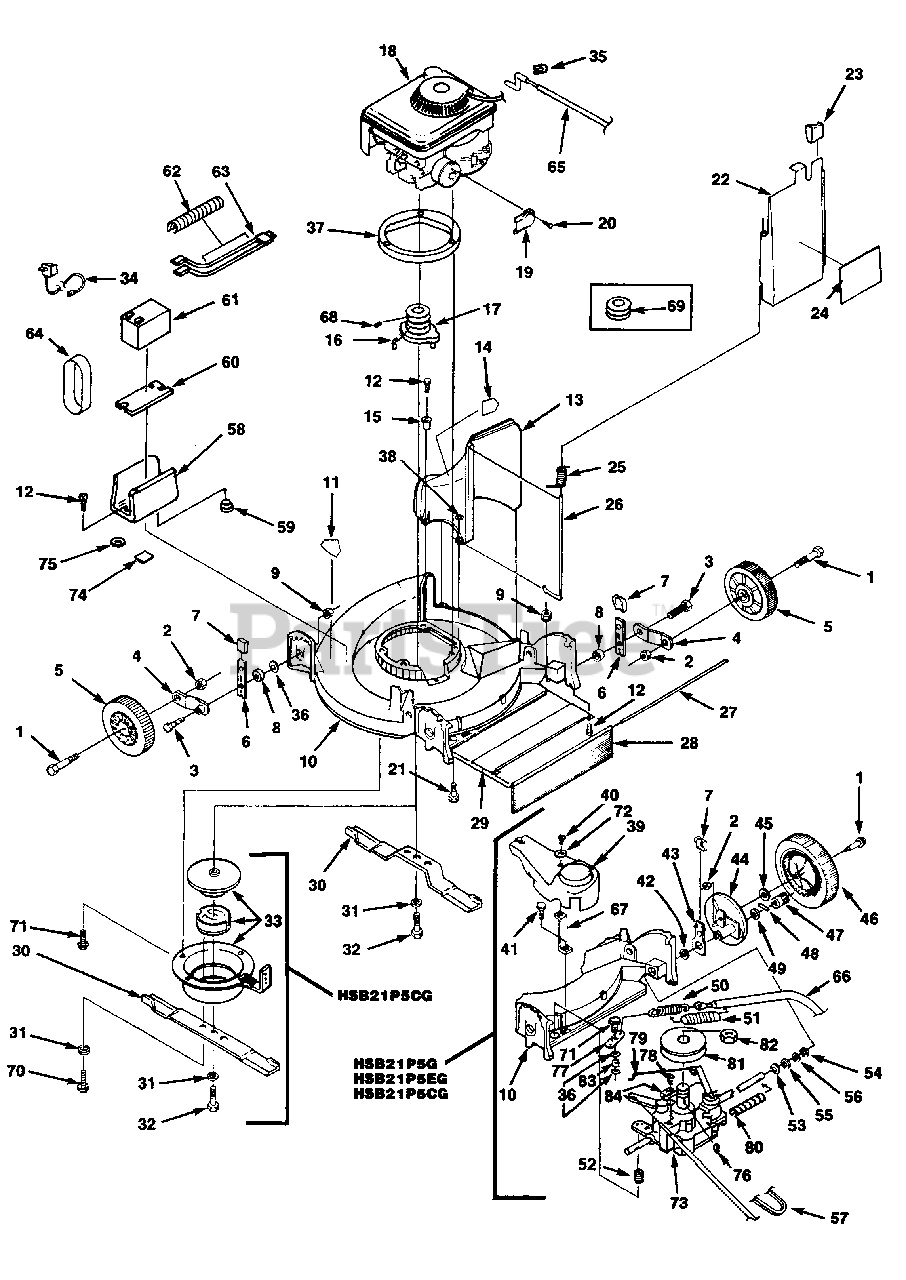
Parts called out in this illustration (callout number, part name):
1	AXLE ASSY.
3	BOLT-Hgt. adj.
4	ARM-Wheel hgt. adj.
5	WHEEL & TIRE
6	SPRING-Index (Front)
7	KNOB-index sprg.
8	SPACER-Wheel hgt. adj.
9	NUT-Flange 5/16-18
10	DECK
11	DECAL-Foot pad
12	SCREW 1/4-20 X 3/4"
13	CHUTE-Discharge
14	DECAL-CPSC
15	EYELET-Simpson
16	KEY-Woodruff
17	ADAPTER-Blade
18	ENGINE
19	DEFLECTOR
20	SCREW-#8-32 X 3/8"
21	SCREW-3/8-16 X 2 1/4"
22	DOOR-Chute
23	KNOB-index sprg.
24	DECAL-Door (warning)
25	SPRING-Chute door
26	PIN-Hinge
27	ROD-Drag flap
28	FLAP-Drag
29	COVER-Drag
30	BAR-Cutter
31	WASHER-Lock 3/8"
32	Screw-Hex hd. 3/8-24 x 1 1/4"
33	CLUTCH-Blade brake
34	BATTERY CHARGER (120V)
35	STOP-Rope
36	WASHER-Flat (5/16")
37	RING-Engine
38	WASHER-Plain (1/4")
39	COVER-Drive
40	Screw 1/4-20 x 3/4
41	Screw Hex #10-16
42	SPACER-Rear hgt. adj.
43	SPRING-index
44	SUPPORT-Drive wheel
46	WHEEL & TIRE
47	PINION (L.H.)
48	Pin-Drive
50	SPRING-Ext.
51	COVER-Spring
52	SPRING-Compression
53	RING-Eaton
57	BELT-Traction
58	HOLDER-Battery
59	BUMPER
60	PAD-Battery
61	BATTERY
62	COVER-Harness
63	LEAD
64	BAND-Rubber
65	ENGINE-Control
66	CABLE-Traction control
67	SUPPORT-Cover
68	SCREW-Set
69	PULLEY-Drive
70	SCREW-Hex hd. 3/8-16 x 1"
71	SCREW-Hex hd. 5/16-18
72	WASHER-Plain
73	GEAR REDUCER (3 Speed)
74	SPACER-Battery holder
75	SPACER
76	KEY-Woodruff
77	BELL CRANK
78	SCREW-5/16-18 x 5/8"
79	LINKAGE-Shift
80	COVER-Drive shaft
81	PULLEY-Gear
82	NUT-Metric (M10)
83	SPACER-Bellcrank
84	CLAMP-Cable
